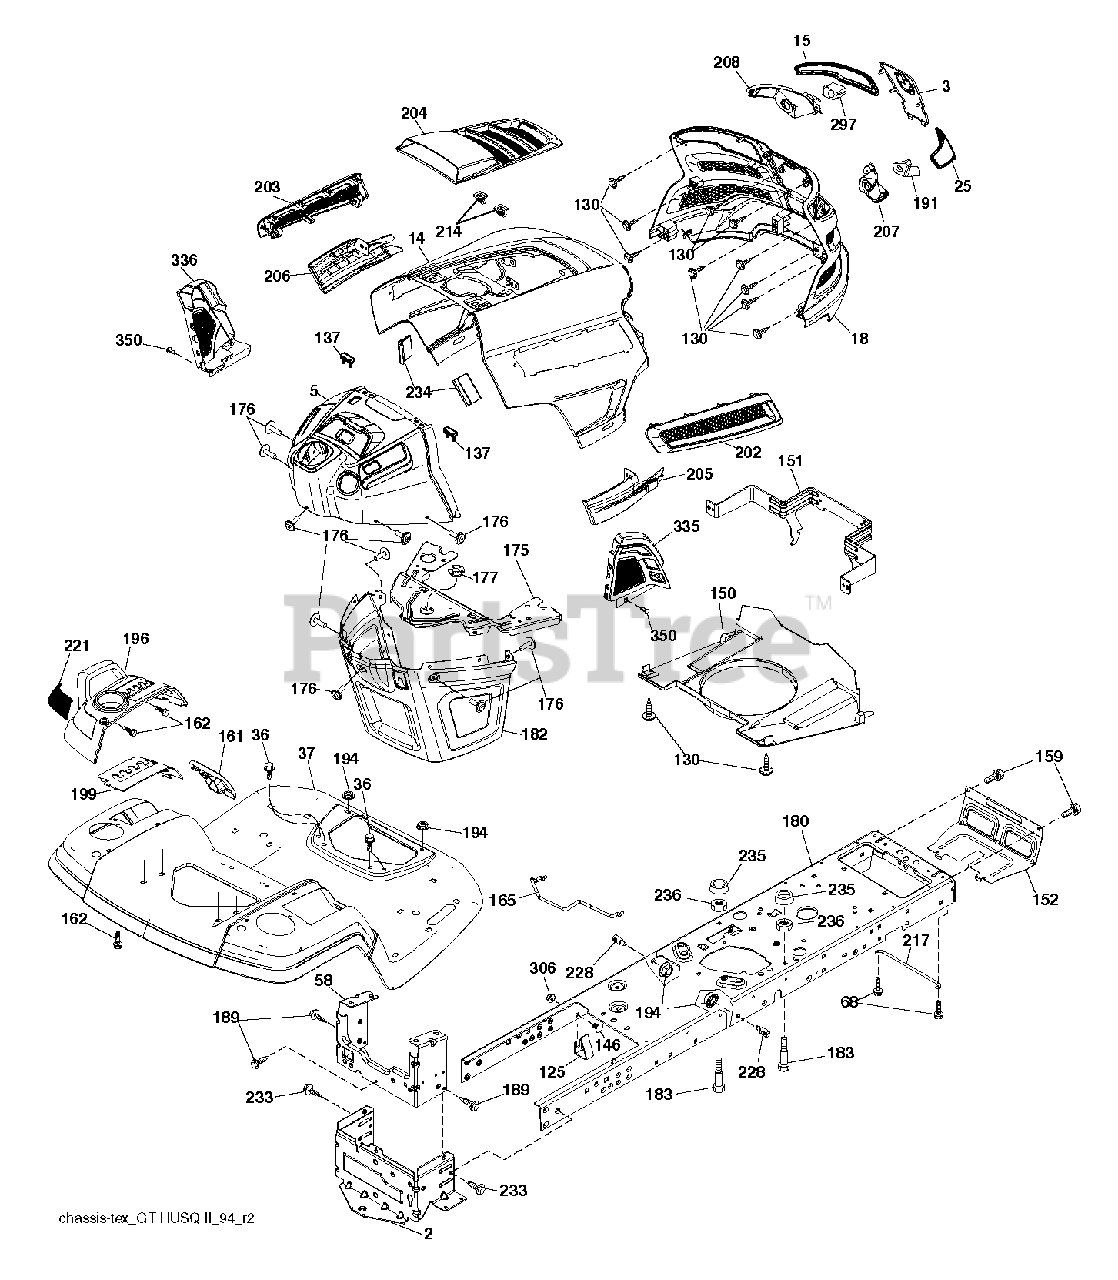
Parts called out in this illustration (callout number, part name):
2	DRAWBAR.LOWER.2PC.18/22
3	APPLIQUE.SUBASM.GT.HUSQ.II
5	DASH.HUSQ2.SM.E.NC.HR.CHG.498
14	HOOD.ASM.HUSQVARNA.GT.TEX.ORAN
15	LENS.HEADLIGHT.LH.GTII.2011
18	GRILLE.SUBSTRATE.2011.
25	LENS.HEADLIGHT.RH.GTII.2011
36	SCREW 5/16"
37	FENDER.PNT.TX.GT.CH/FW/DL.HUSQ
58	DRAWBAR.UPPER.2PC,LRG.FENDER
68	SCREW LT
125	CLIP.FUEL.LINE
130	SCREW.#10 X 0.750.BOS
137	BUMPER DASH
146	BOLT.RDHD.SHT.SQNK.3/8-16X5/8
150	AIR.DUCT.GTV.BLACK
151	BRACKET.PIVOT.HOOD.GT.HUSQ.II
152	SHIELD.BROWNING.PNT.GT.V2
159	SCREW, 3/8-16X3/4
161	CONSOLE.WINDOW.FUEL.HUSQ.GT
162	SCREW.HI-LO.CONSOLE
165	SUPPORT.TANK.REAR.B/TE
175	PLATE.CROSSMEMBER.HUSQ
176	SCREW.#10-24X5/8.RN.QU
177	BUSHING, STEERING
180	CHASSIS.TEX.BOLTED
182	DASH.LOWER.COMMON.12V.ADAPTOR
183	BOLT.5/16-18X1-1/4 FULL THD
189	SCREW
191	INSERT.REFLECTIVE.RH.HUSQ.GTII
194	NUT LOCK HEX FLANGE 5/16-18
196	CONSOLE.ASM.DECKLIFT.HUSQGT.DL
199	PLATE.DECK.LIFT.HUSQVARNA.GT
202	VENT.SIDE.RH.GT.HUSQ.II.
203	VENT.SIDE.LH.GT.HUSQ.II.498
204	VENT.TOP.HUSQ.GT2
205	SIDE.TRIM.RH.GT.HUSQ.II
206	SIDE.TRIM.LH.GT.HUSQ.II.GRAY
207	BEZEL LIGHT.RH.GT.II.MYLAR
208	BEZEL LIGHT.LH.GT.II.MYLAR
214	CLIP.RETAINER.TINNER.
217	ROD.PIVOT.HOOD
221	REFLECTOR.LH.TEX GT HU
228	STUD.FASTNER.W/ANTI-ROTATE
233	BOLT.SHOULDER
234	BUMPER.HOOD.TEX.HUSQVARNA
235	SPACER FENDER
236	NUT.CENTERLOCK.5/16-
297	INSERT.REFLECTIVE.LH.HUSQ.GTII
306	NUT LOCK FLG 3/8-16 UNC
335	COVER.LOWER.DASH.RH.BLACK
336	COVER-LH.LOWER.DASH.GT2.BLACK
350	CLIP.X-MAS.TREE
